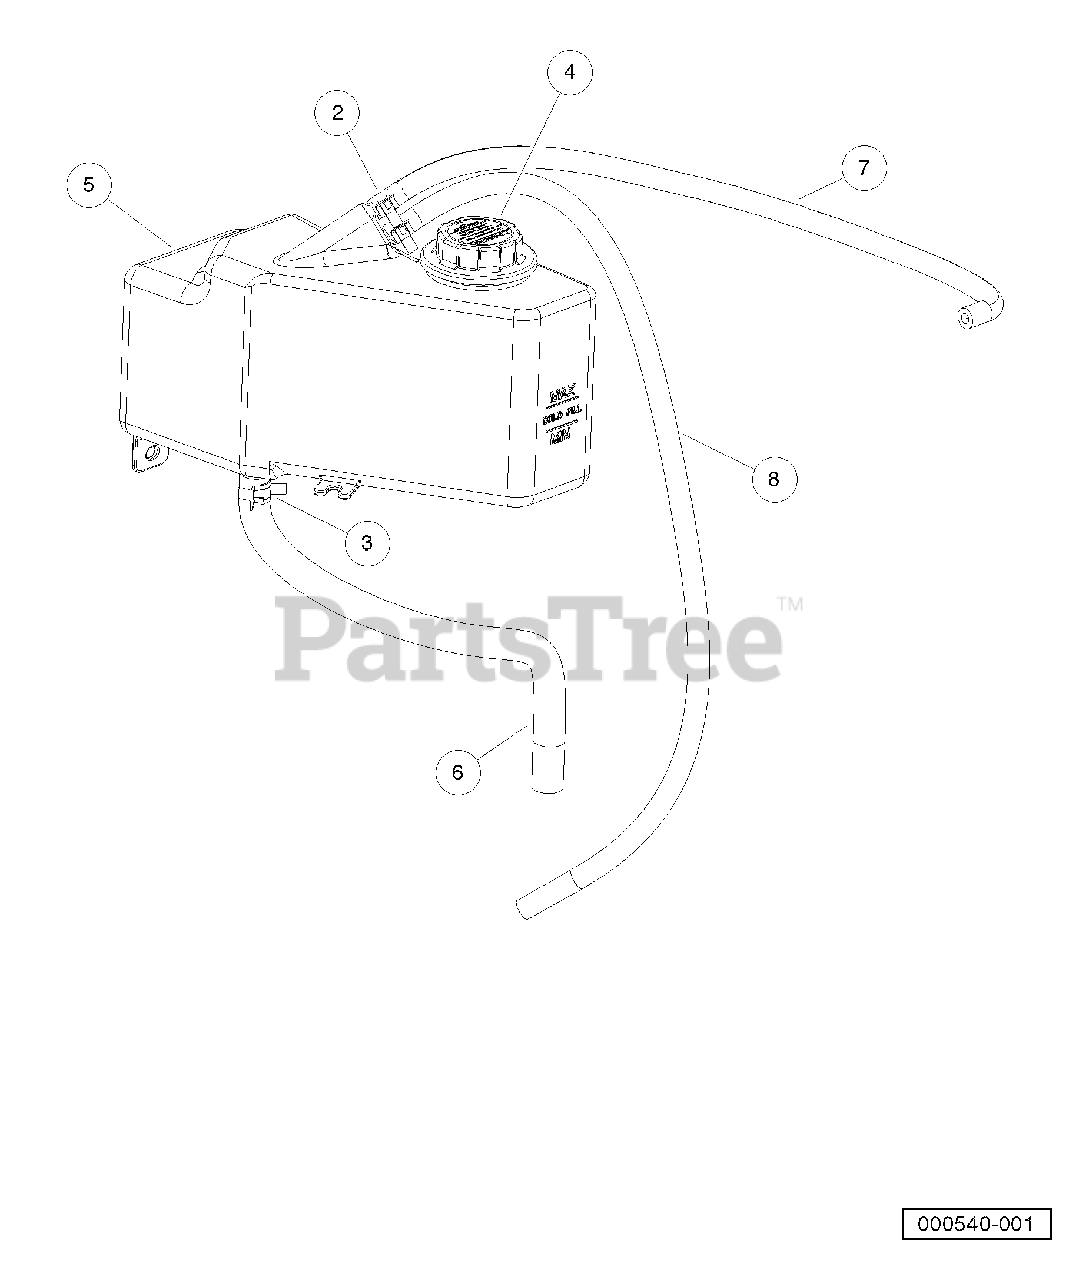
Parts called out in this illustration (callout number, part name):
1	Asm, Coolant Bottle
2	Clamp, Hose, CTB 15mm
3	Clamp, Hose, CTB 22mm
4	Cap, Radiator
5	Bottle, Coolant
6	Hose, Cut, 5/8, 445
7	Hose, Cut, Coolant, 700
8	Hose, Cut, Coolant, 1100
